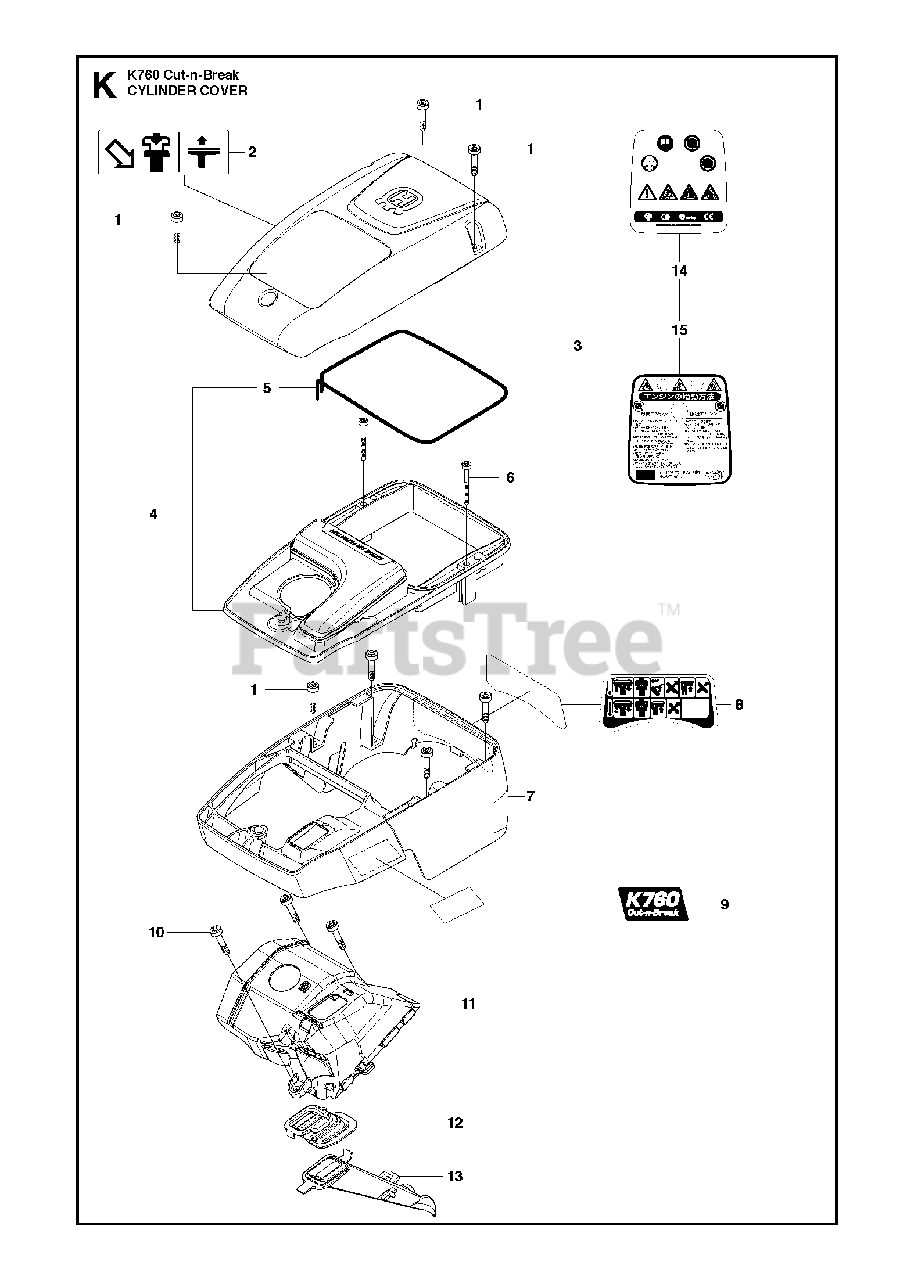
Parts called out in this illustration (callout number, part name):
1	SCREW ITXSCM
3	FILTER COVER ASSYincl. 14
4	FILTER HOLDER ASSYIncl. 5
4	FILTER HOLDER ASSYOIL GUARD
5	SEALING STRIP
6	SCREW ITXSCM
7	CYLINDER COVER
10	SCREW ITXSCM
12	BELLOWS
